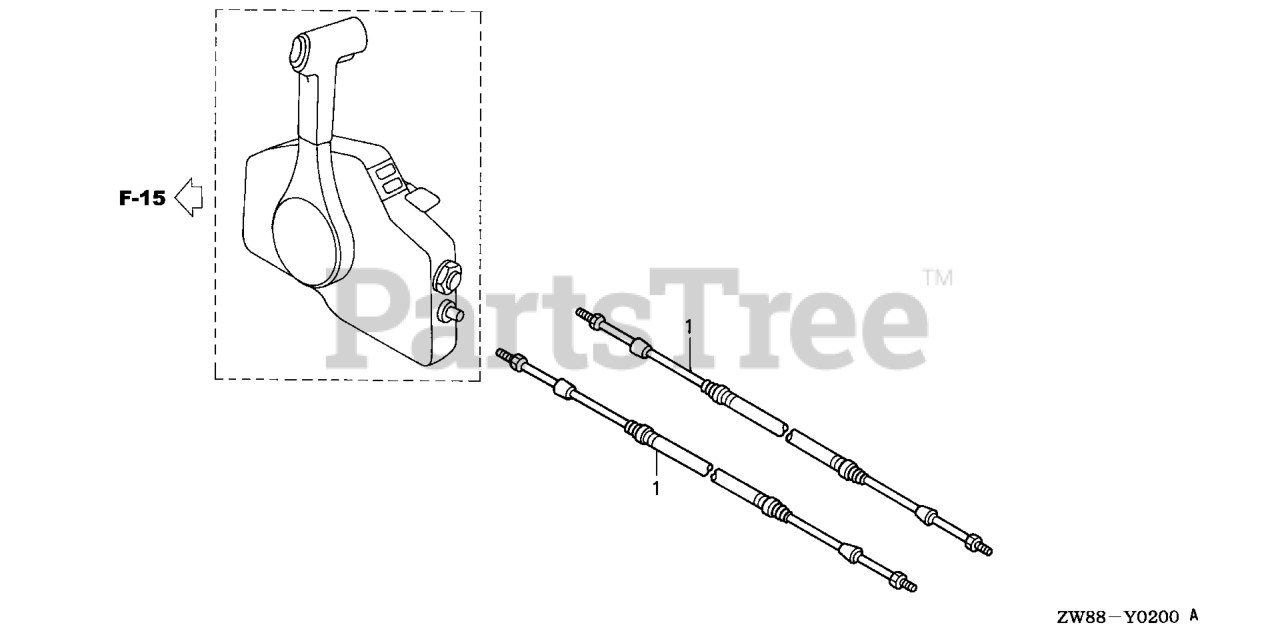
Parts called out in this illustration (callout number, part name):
1	CABLE ASSY., PUSH-PULL (33HPC-8FT)
1	CABLE, REMOTE CONTROL (10'') (LOW FRICTION)
1	CABLE ASSY., PUSH-PULL (33C-5FT)
1	CABLE, REMOTE CONTROL (11'') (LOW FRICTION)
1	CABLE ASSY., PUSH-PULL (33C-6FT)
1	CABLE, REMOTE CONTROL (12'') (LOW FRICTION)
1	CABLE ASSY., PUSH-PULL (33HPC-12FT)
1	CABLE ASSY., PUSH-PULL (33C-7FT)
1	CABLE, REMOTE CONTROL (13'') (LOW FRICTION)
1	CABLE, REMOTE CONTROL (14'') (LOW FRICTION)
1	CABLE ASSY., PUSH-PULL (33HPC-14FT)
1	CABLE ASSY., PUSH-PULL (33C-9F T)
1	CABLE, REMOTE CONTROL (15'') (LOW FRICTION)
1	CABLE ASSY., PUSH-PULL (33C-10FT)
1	CABLE, REMOTE CONTROL (16'') (LOW FRICTION) (NOT AVAILABLE)
1	CABLE ASSY., PUSH-PULL (33HPC-16FT)
1	CABLE ASSY., PUSH-PULL (33C-11FT)
1	CABLE, REMOTE CONTROL (17'') (LOW FRICTION)
1	CABLE ASSY., PUSH-PULL (33HPC-17FT)
1	CABLE ASSY., PUSH-PULL (33C-12 FT)
1	CABLE, REMOTE CONTROL (18') (LOW FRICTION) (NOT AVAILABLE)
1	CABLE ASSY., PUSH-PULL (33C-13 FT)
1	CABLE, REMOTE CONTROL (1 9'') (LOW FRICTION)
1	CABLE ASSY., PUSH-PULL (33C-14FT)
1	CABLE, REMOTE CONTROL (20'') (LOW FRICTION) (NOT AVAILABLE)
1	CABLE ASSY., PUSH-PULL (33HPC-20FT)
1	CABLE ASSY., PUSH-PULL (33C-15 FT)
1	CABLE, REMOTE CONTROL (21') (LOW FRICTION)
1	CABLE, REMOTE CONTROL (22') (LOW FRICTION) (NOT AVAILABLE)
1	CABLE ASSY., PUSH-PULL (33HPC-22FT)
1	CABLE ASSY., PUSH-PULL (33C-17 FT)
1	CABLE, REMOTE CONTROL (2 3'') (LOW FRICTION)
1	CABLE ASSY., PUSH-PULL (33C-18 FT)
1	CABLE, REMOTE CONTROL (24') (LOW FRICTION) (NOT AVAILABLE)
1	CABLE ASSY., PUSH-PULL (33C-19FT)
1	CABLE, REMOTE CONTROL (25') (LOW FRICTION)
1	CABLE ASSY., PUSH-PULL (33HPC-25FT)
1	CABLE, REMOTE CONTROL (26') (LOW FRICTION)
1	CABLE ASSY., PUSH-PULL (33C-21FT)
1	CABLE, REMOTE CONTROL (27') (LOW FRICTION)
1	CABLE, REMOTE CONTROL (28') (LOW FRICTION) (NOT AVAILABLE)
1	CABLE ASSY., PUSH-PULL (33C-23FT)
1	CABLE, REMOTE CONTROL (2 9') (LOW FRICTION)
1	CABLE ASSY., PUSH-PULL (33C-24FT)
1	CABLE, REMOTE CONTROL (30') (LOW FRICTION) (NOT AVAILABLE)
1	CABLE, REMOTE CONTROL (31') (LOW FRICTION)
1	CABLE ASSY., PUSH-PULL (33C-26FT)
1	CABLE, REMOTE CONTROL (32') (LOW FRICTION) (NOT AVAILABLE)
1	CABLE ASSY., PUSH-PULL (33C-27FT)
1	CABLE, REMOTE CONTROL (33') (LOW FRICTION)
1	CABLE ASSY., PUSH-PULL (33C-28FT)
1	CABLE, REMOTE CONTROL (34') (LOW FRICTION)
1	CABLE ASSY., PUSH-PULL (33C-29FT)
1	CABLE, REMOTE CONTROL (35') (LOW FRICTION)
1	CABLE ASSY., PUSH-PULL (33C-30FT)
1	CABLE ASSY., PUSH-PULL (33C-31FT)
1	CABLE ASSY., PUSH-PULL (33C-32FT)
